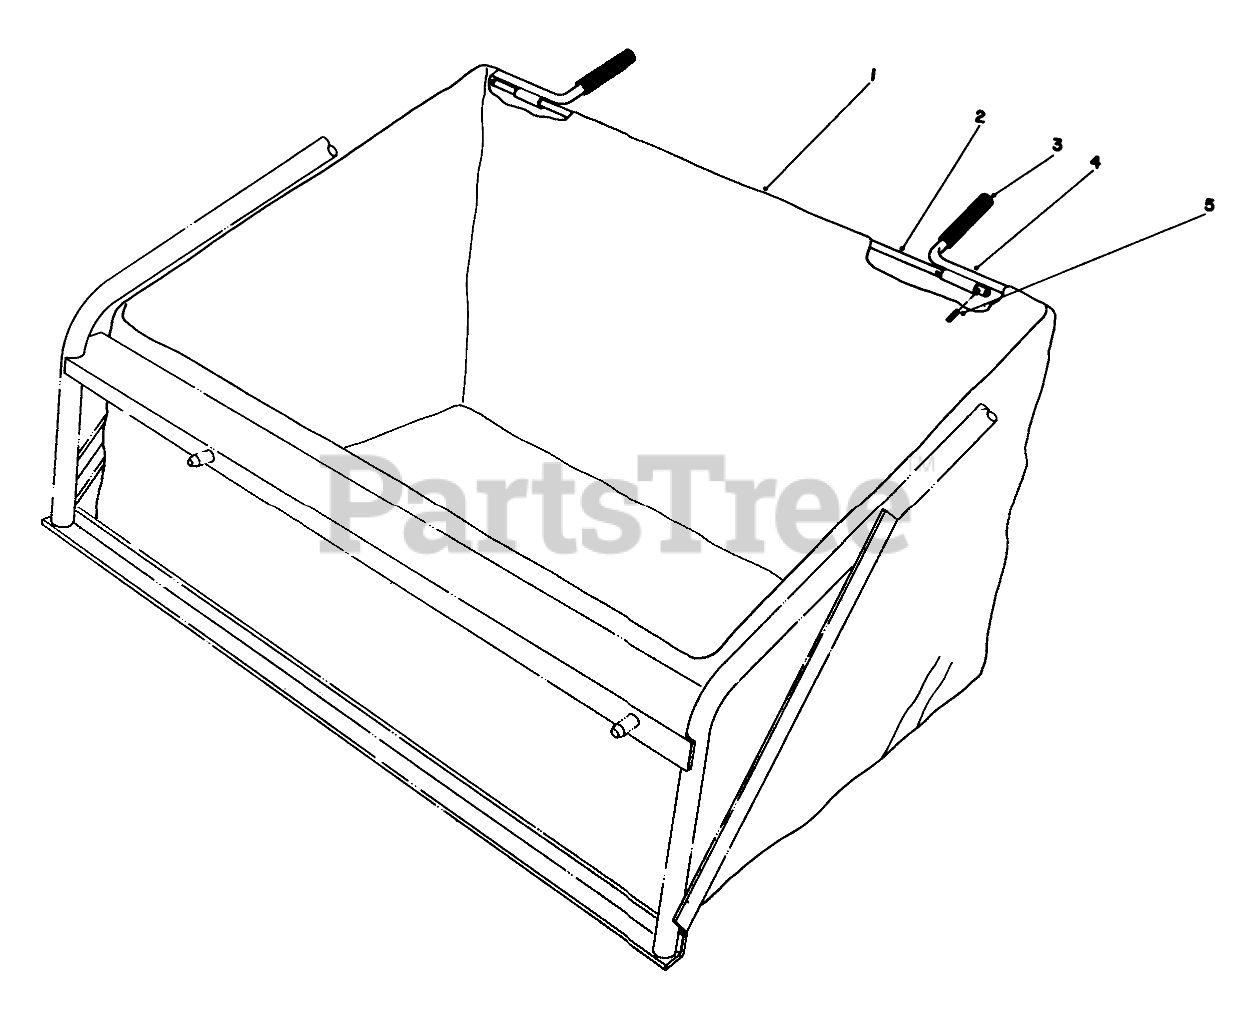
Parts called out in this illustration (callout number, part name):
1	Bag-Leaf Catcher
2	BAG FRAME ROD
3	Grip-Leaf Bag Handle
4	BAG FRAME WA B
5	PIN-ROLL
